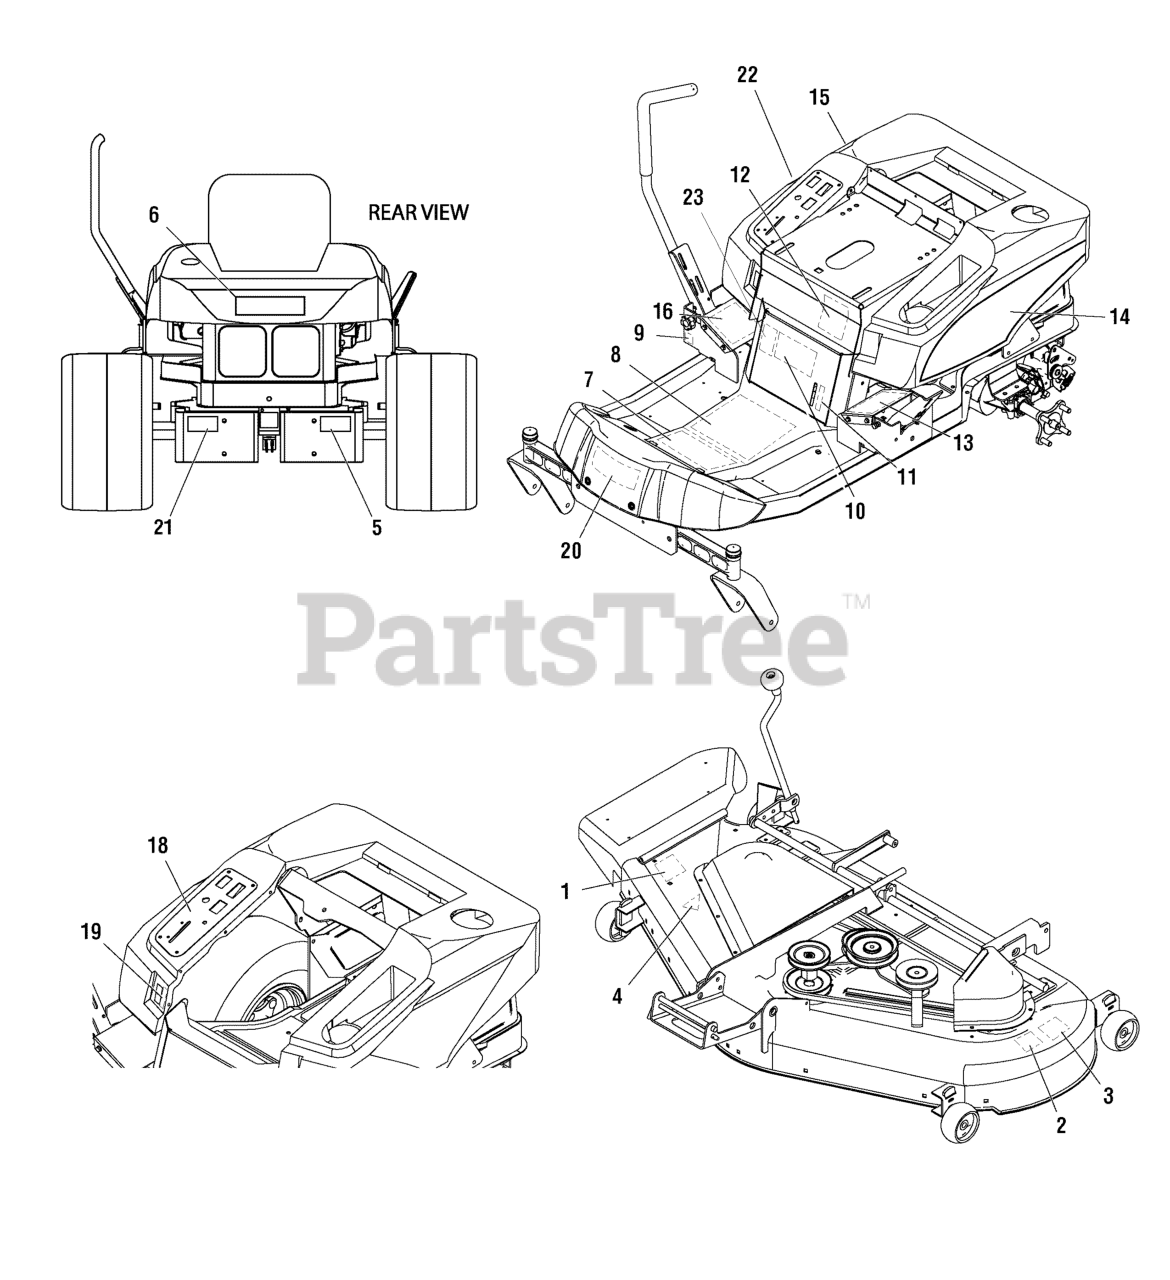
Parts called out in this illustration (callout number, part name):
1	DECAL, Danger Do Not Operate without Deflector (English/French)
2	DECAL, Danger Do Not Put Hands/Feet in Mower (English/French)
3	DECAL, 52"
4	DECAL, OPEI Certified ANSI
5	DECAL, Transmission Release Instructions (English/French)
6	DECAL, Craftsman ZTS
7	DECAL, Operator Instructions Upper (English/French)
8	DECAL, Operator Instructions Lower (English/French)
9	DECAL, Tracking Adjustment
10	DECAL, Powered by 26HP
11	DECAL, Height of Cut
12	DECAL, Service Parts Kohler, 26HP
13	DECAL, Handle Control, L.H. 26HP
14	DECAL, Seat Deck L.H. Craftsman ZTS
15	DECAL, Seat Deck R.H. Craftsman ZTS
16	DECAL, Handle Control R.H.
18	DECAL, Instrument Panel
19	DECAL, Height of Cut
20	DECAL, Craftsman Logo
21	DECAL, Caution Cut Hazard
22	DECAL, Hot Surfaces
23	DECAL, ZT PARKING BRAKE
